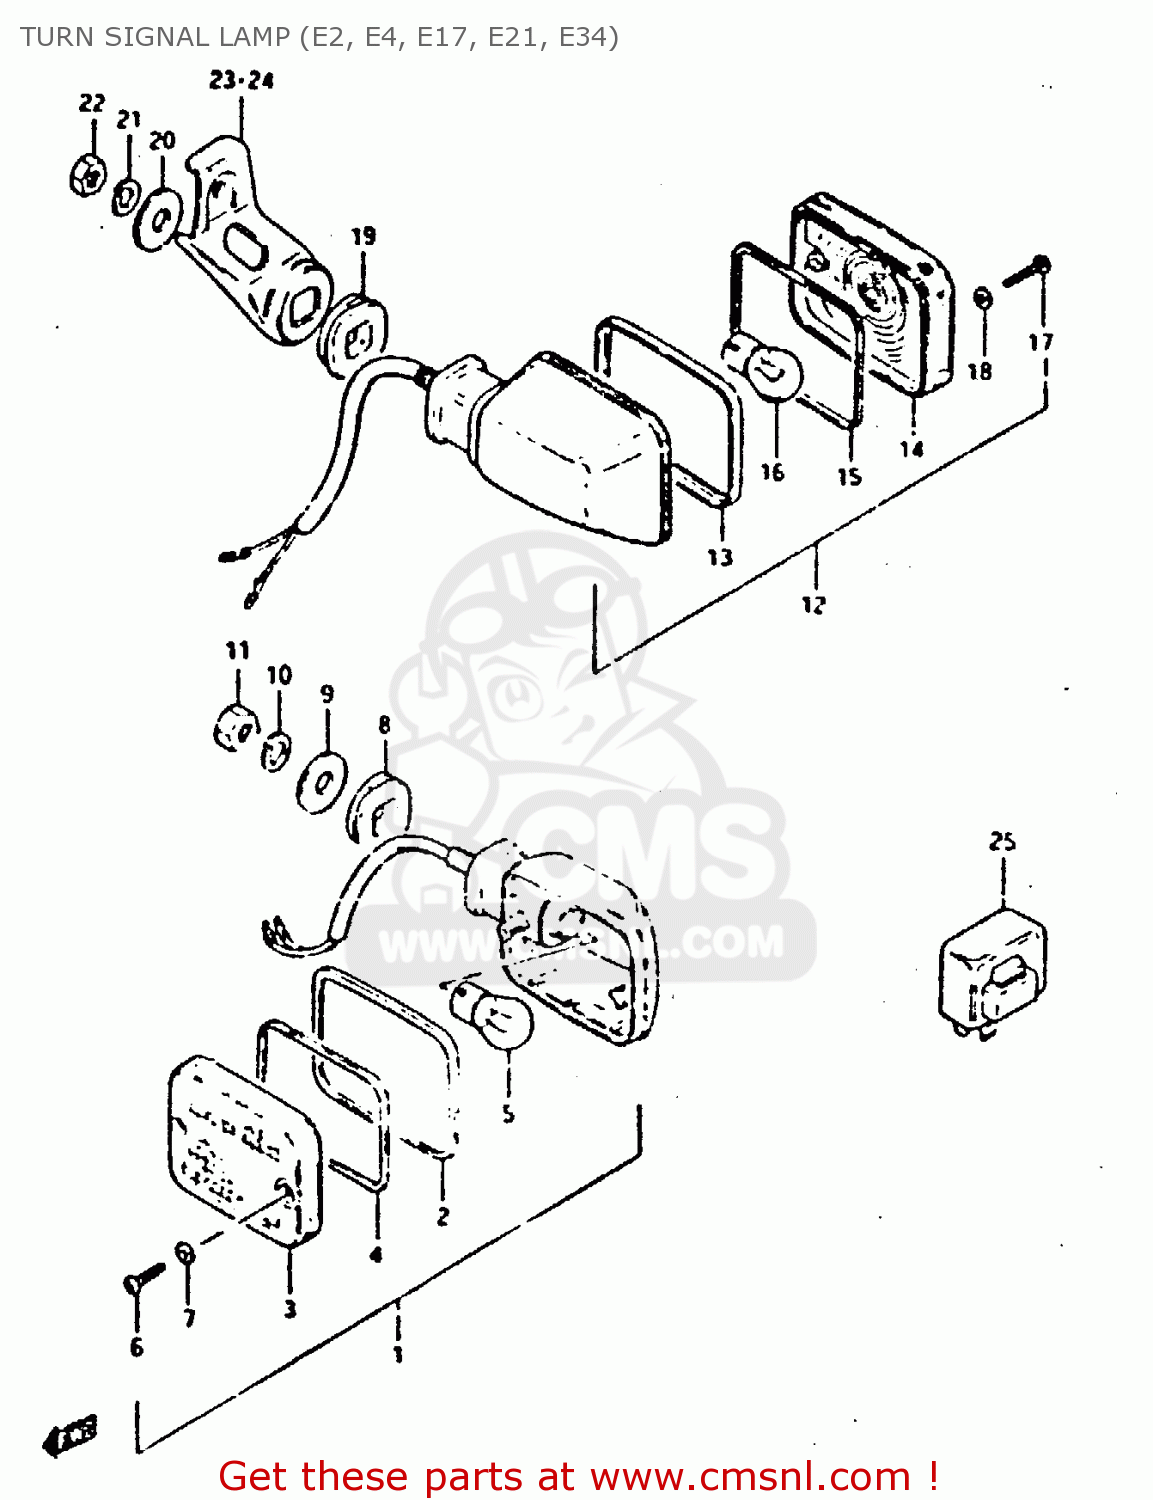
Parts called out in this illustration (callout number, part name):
1	LAMP ASSY,FR T
2	RIM
3	LENS
4	GASKET (NAS)
5	BULB 12V 21W
6	SCREW
7	GASKET (NAS)
8	CUSHION
9	WASHER (10.5X30X2.3)
10	LOCK WASHER
11	NUT
12	LAMP, REAR TURN SIGNAL
13	RIM
14	LENS
15	GASKET (NAS)
16	BULB 12V 21W
17	SCREW
18	GASKET (NAS)
19	CUSHION
20	WASHER (10.5X30X2.3)
21	LOCK WASHER
22	NUT
23	BRACKET,REAR TURN SIGNAL
24	BRACKET,REAR TURN SIGNAL
25	RELAY,TURN SIGNAL
